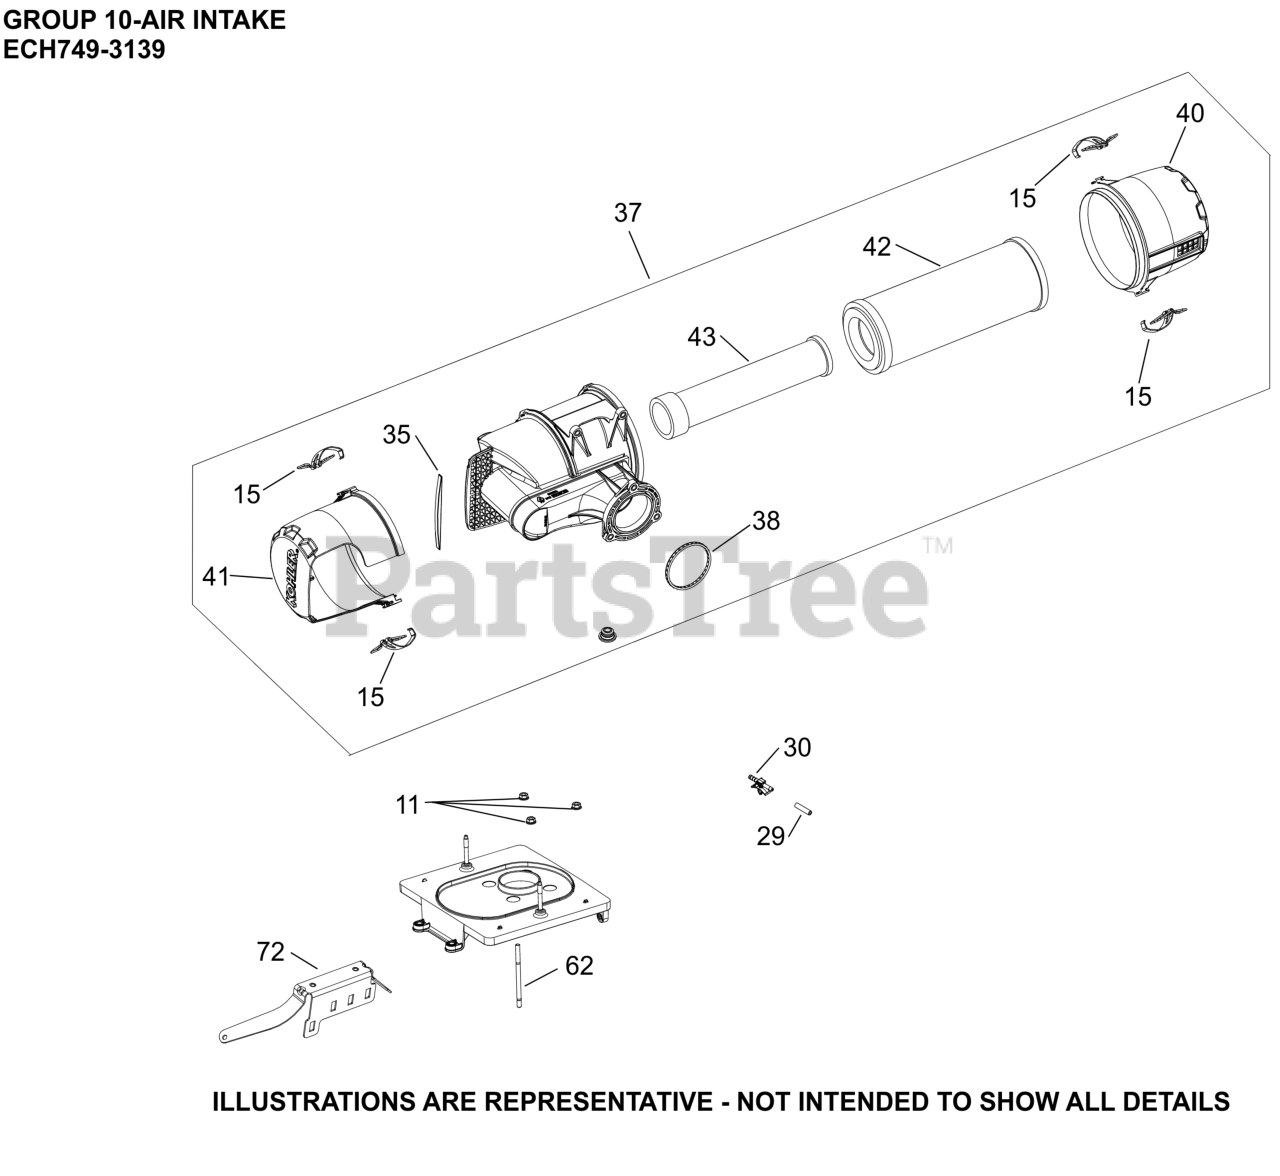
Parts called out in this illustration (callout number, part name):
11	NUT, FLG M6X1.0
15	CLIP ASSEMBLY
29	CAP, MASKING
30	CONNECTOR, EVAPORATIVE
35	DAMPER, FOAM INSERT
37	CLEANER, ASSEMBLY AIR - ETB
38	O-RING (HDAC SEAL-EFI)
40	COVER, AIR FILTER
41	COVER, RAIN CAP
42	ELEMENT, AIR FILTER - PRIMARY
43	ELEMENT, AIR FILTER - SAFETY
72	BRACKET, HDAC SUPPORT (ETB)
